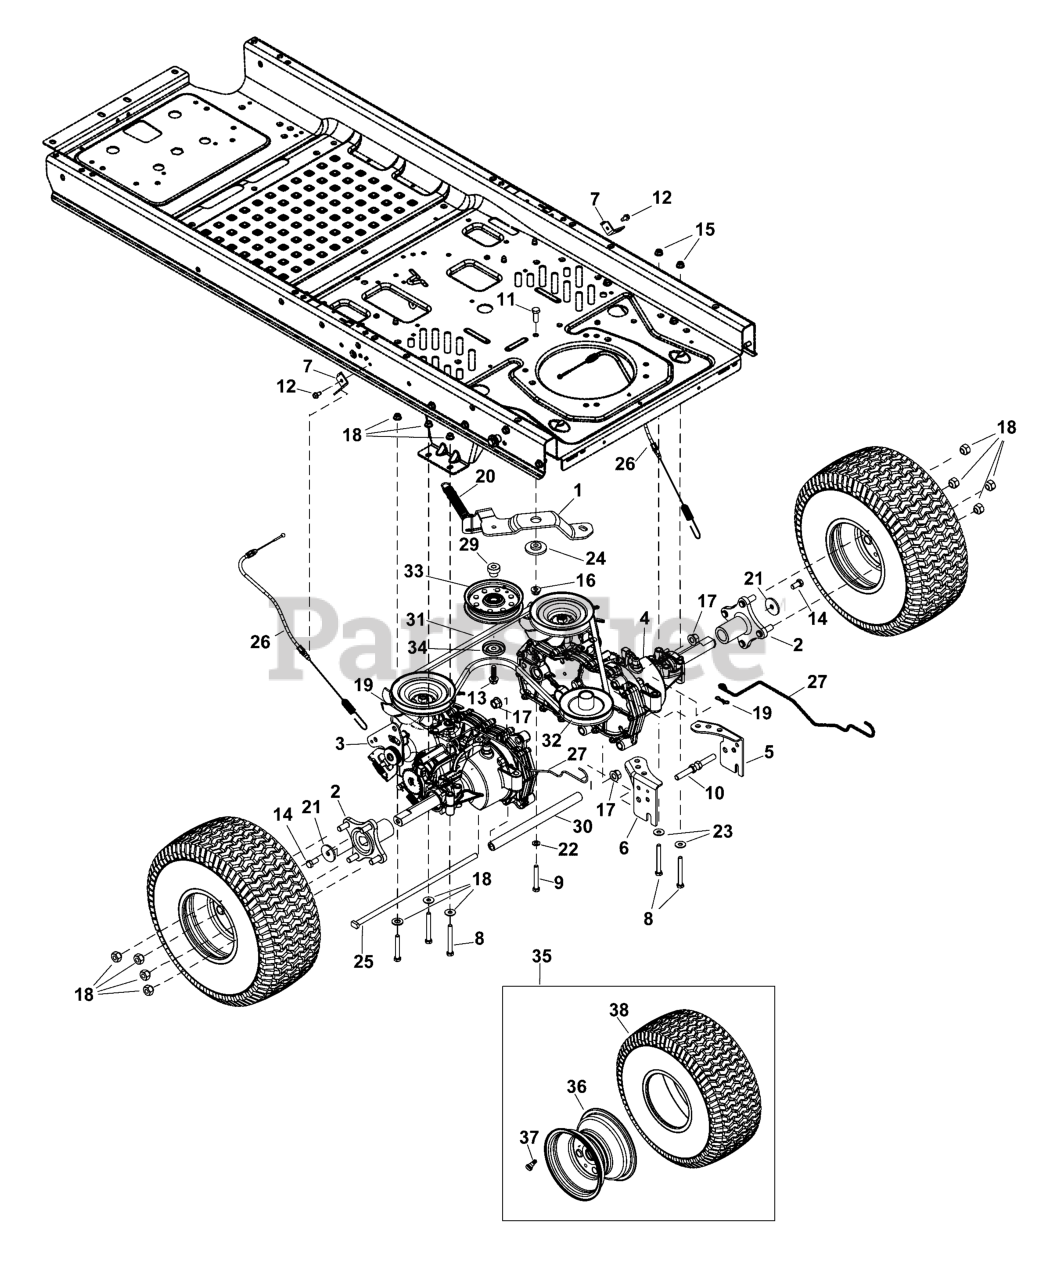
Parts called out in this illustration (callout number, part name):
1	BRACKET, Idler
2	ASSEMBLY, Wheel Hub
3	ASSEMBLY, Hydro Transmission (LH)
4	ASSEMBLY, Hydro Transmission (RH)
5	BRACKET, Transmission Mounting (RH)
6	BRACKET, Transmission Mounting (LH)
7	BRACKET, Brake Cable
8	SCREW, 5/16-18 X 2.75, Hex
9	SCREW, 5/16-18 X 2.25, Hex, GR5
10	SCREW, 7/16-20 X 1.75 GR 5
11	SCREW, 3/8-16 X 1 GR5
12	SCREW, TT, 1/4-20 x 1/2
13	SCREW, 3/8-16 X1.250
14	SCREW, 3/8-16 X .75 GR 5
16	NUT, 3/8-16, Flanged Lock, GR5
17	NUT, Flange Lock
18	NUT, 7/16-14, Lug
19	PIN, 1/4-5/16, Bow Tie Cotter
20	SPRING, .75 DIA X 5.87 RZT/F, Extension
21	WASHER, .390X1.500X.134, Flat
22	WASHER, 5/16, Flat
23	WASHER, 5/16, Flat
24	SPACER, Shoulder
25	ROD, Support Tube
26	CABLE, Park Prake
27	ROD, Hydro Bypass
29	SPACER, Shoulder
30	TUBE, Support
31	BELT, A X 67, Transmission Drive
32	PULLEY, Transmission Drive
33	PULLEY, 4.25 DIA, Idler
34	PULLEY CAP, Idler Pulley
35	ASSEMBLY, Wheel (18 X 8.5-8)
36	ASSEMBLY, Rear Rim
37	VALVE, Stem - Tubless
38	TIRE, 18 X 9.5 X 8 SQ SH
